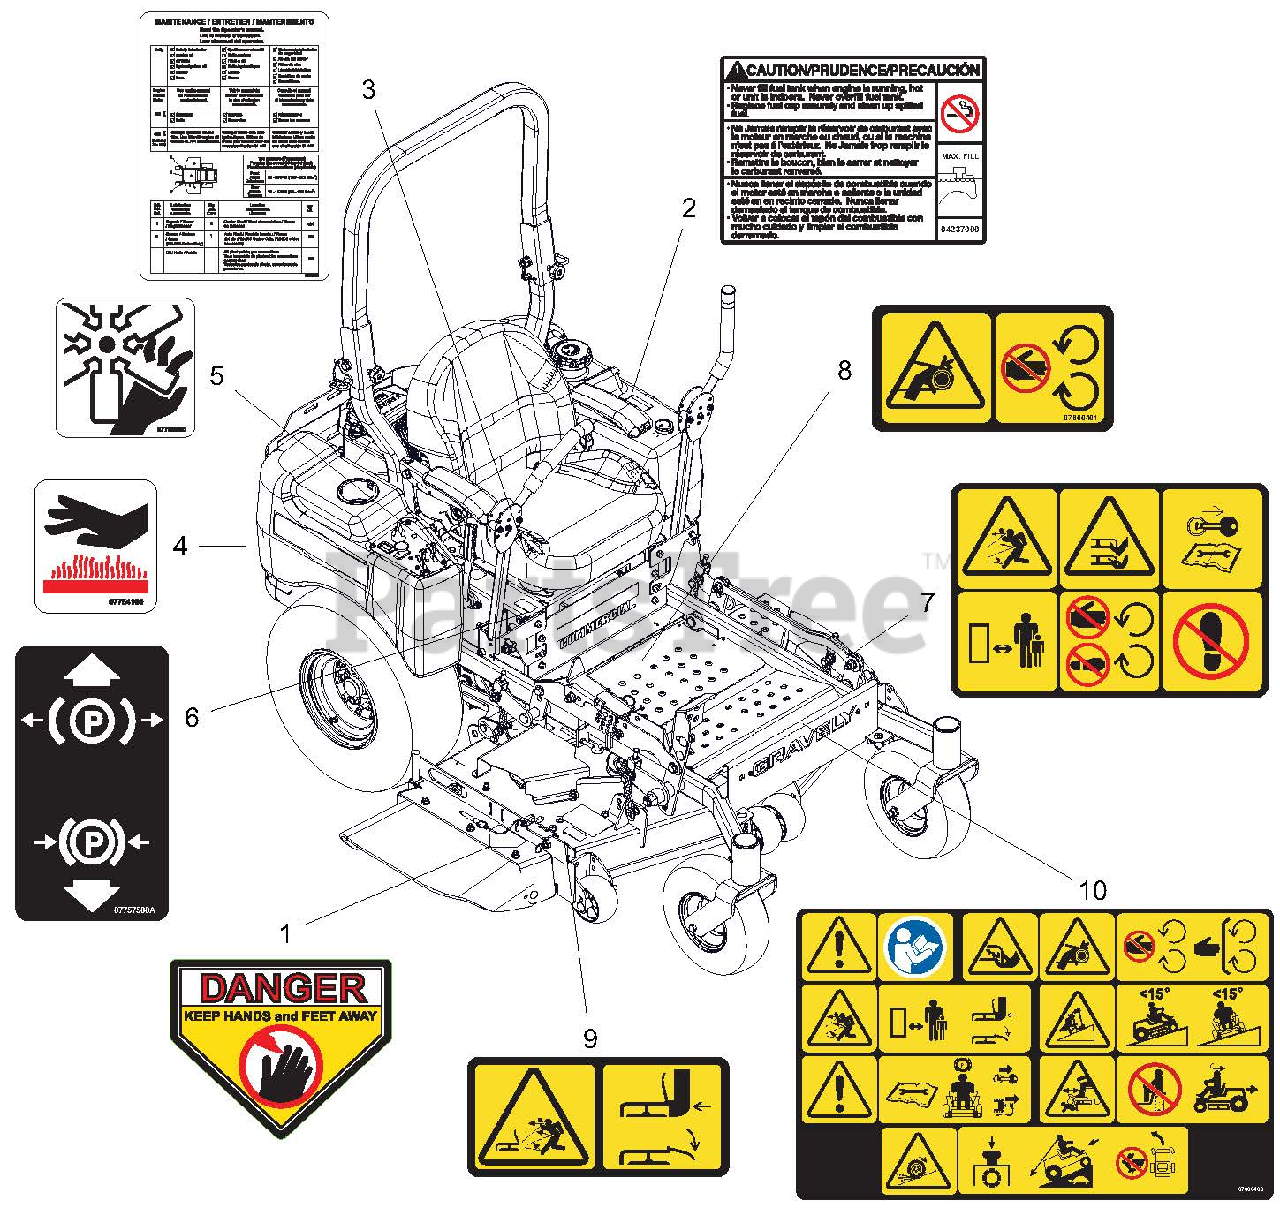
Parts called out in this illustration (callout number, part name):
1	DECAL, DANGER
2	DECAL, FUEL WARNING
3	DECAL, MAINTENANCE INSTRUCTIONS
4	DECAL HOT SURFACE
5	DECAL, DANGER - FAN
6	DECAL, PARKING BRAKE LEVER
7	DECAL, SAFETY - MOWER DECK
8	DECAL, SAFETY - GUARDING
9	DECAL, SAFETY - DECK GUARDING
10	DECAL, MAIN SAFETY, COMMERCIAL
